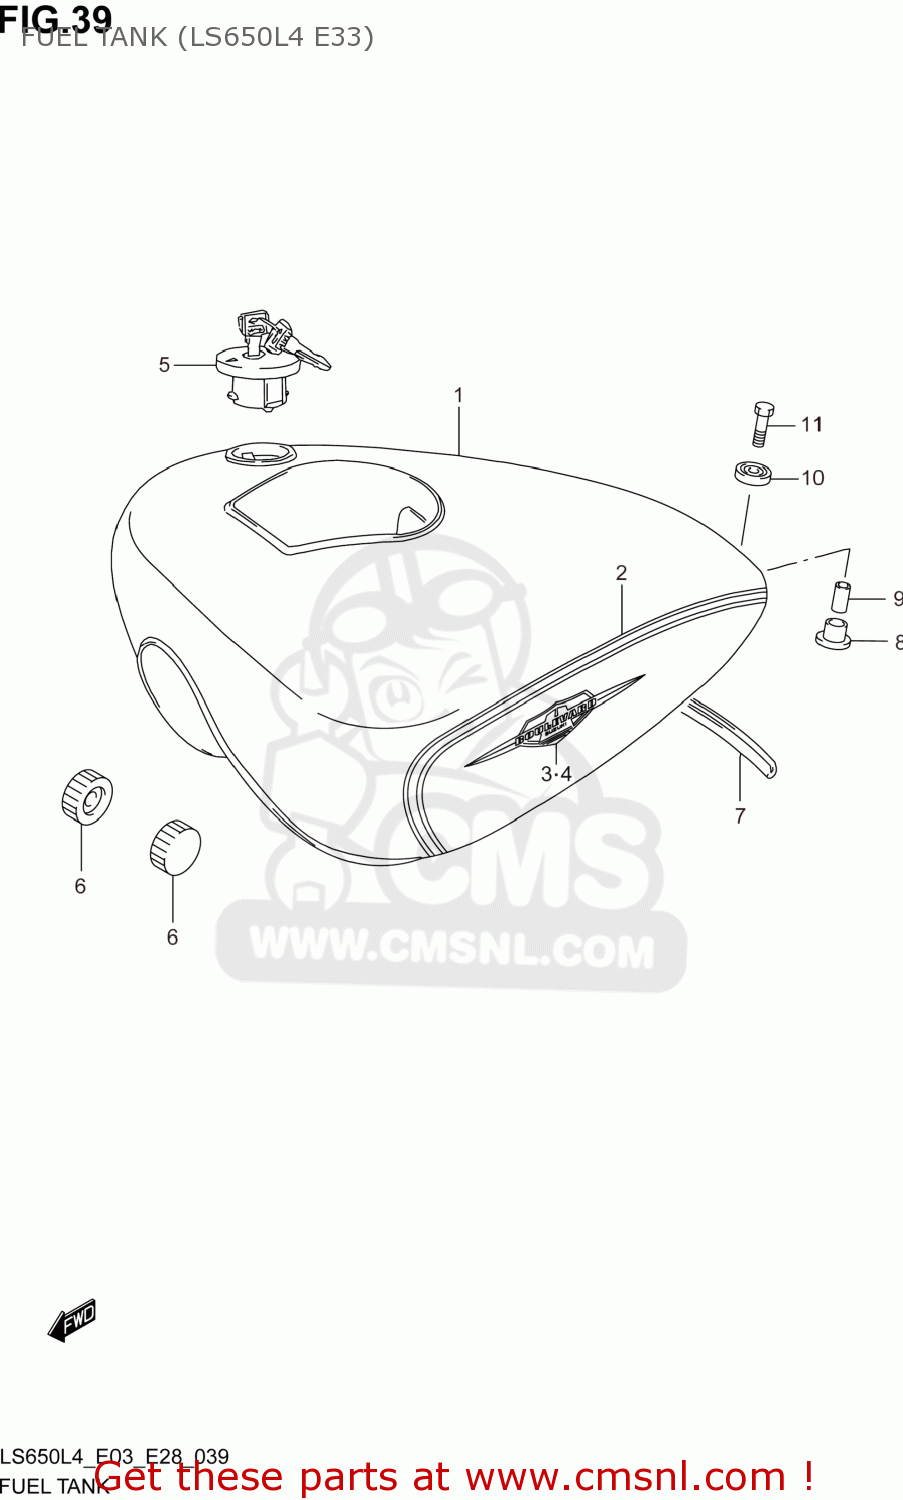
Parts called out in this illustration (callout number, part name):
1	TANK ASSY,FUEL
2	TAPE SET,FUEL TANK
3	EMBLEM,FUEL TANK,R
4	EMBLEM,FUEL TANK,L
5	CAP SET,FUEL TANK
6	CUSHION
7	MOLDING,FUEL TANK RR
8	CUSHION
9	SPACER(6.5X9X18)
10	CUSHION
11	BOLT
